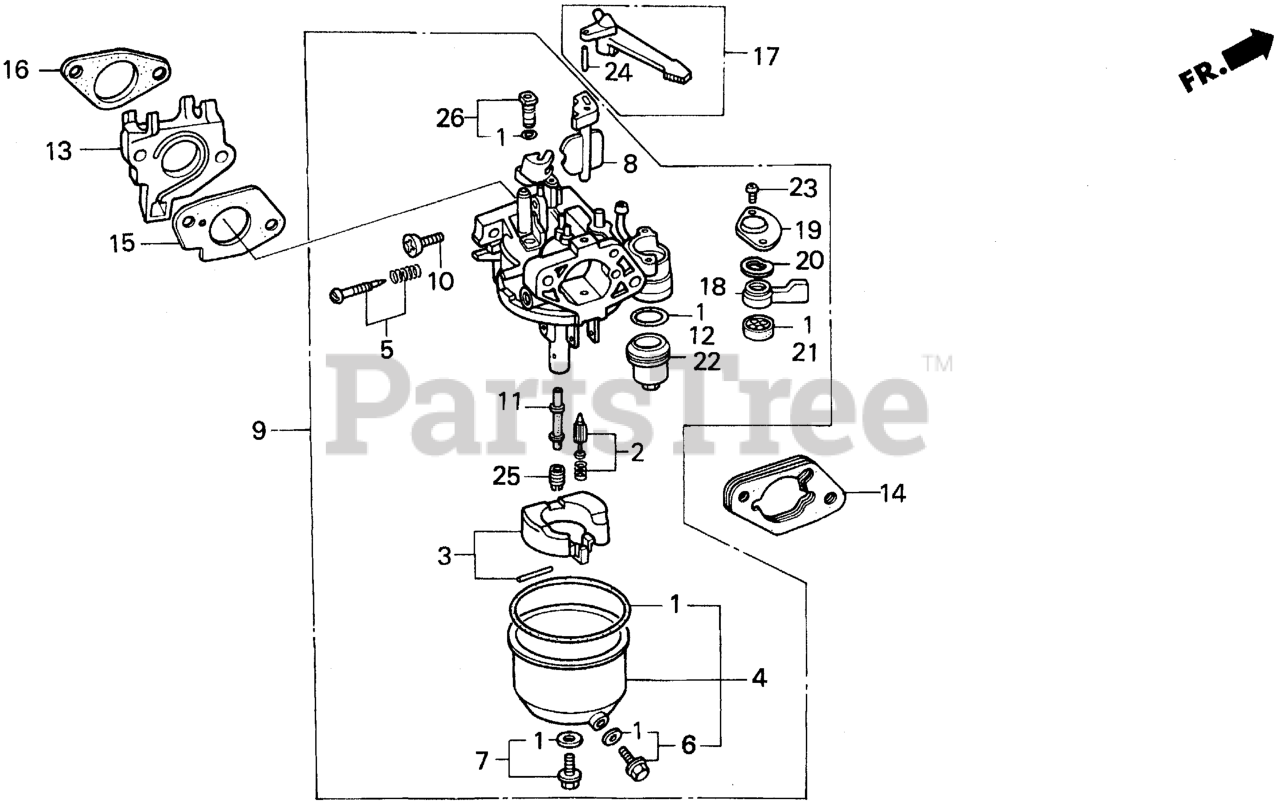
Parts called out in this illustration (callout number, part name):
1	GASKET SET
1	GASKET SET (INCLUDE 16173-001-004) (INCLUDES 16173-001-004)
2	VALVE SET, FLOAT
3	FLOAT SET
4	CHAMBER SET, FLOAT
5	SCREW SET, PILOT (Honda Code 1441500). (CARBURETOR NO.)
6	SCREW SET, DRAIN (Honda Code 1672187). (CARBURETOR NO.)
7	SCREW SET B
7	SCREW SET
8	CHOKE SET
9	CARBURETOR ASSY. (BE30B C)
9	CARBURETOR ASSY. (BE30B E)
10	SCREW, THROTTLE STOP
11	NOZZLE, MAIN
12	GASKET, FUEL STRAINER CUP
13	INSULATOR, CARBURETOR
14	SPACER, CARBURETOR
15	GASKET, CARBURETOR
16	GASKET, INSULATOR
17	LEVER, CHOKE (STD)
18	LEVER, VALVE
19	PLATE, LEVER SETTING (CARBURETOR NO.)
20	SPRING, PETCOCK LEVER (CARBURETOR NO.)
21	GASKET, VALVE
22	CUP, FUEL STRAINER
23	SCREW, PAN (3X8)
23	SCREW, PAN (3X8) (CARBURETOR NO.)
24	PIN, SPRING (2X12)
25	JET, MAIN (#92) Use from Engine SN BB36B A.
25	JET, MAIN (#95)
25	JET, MAIN (#98)
26	JET SET, PILOT (#35)
